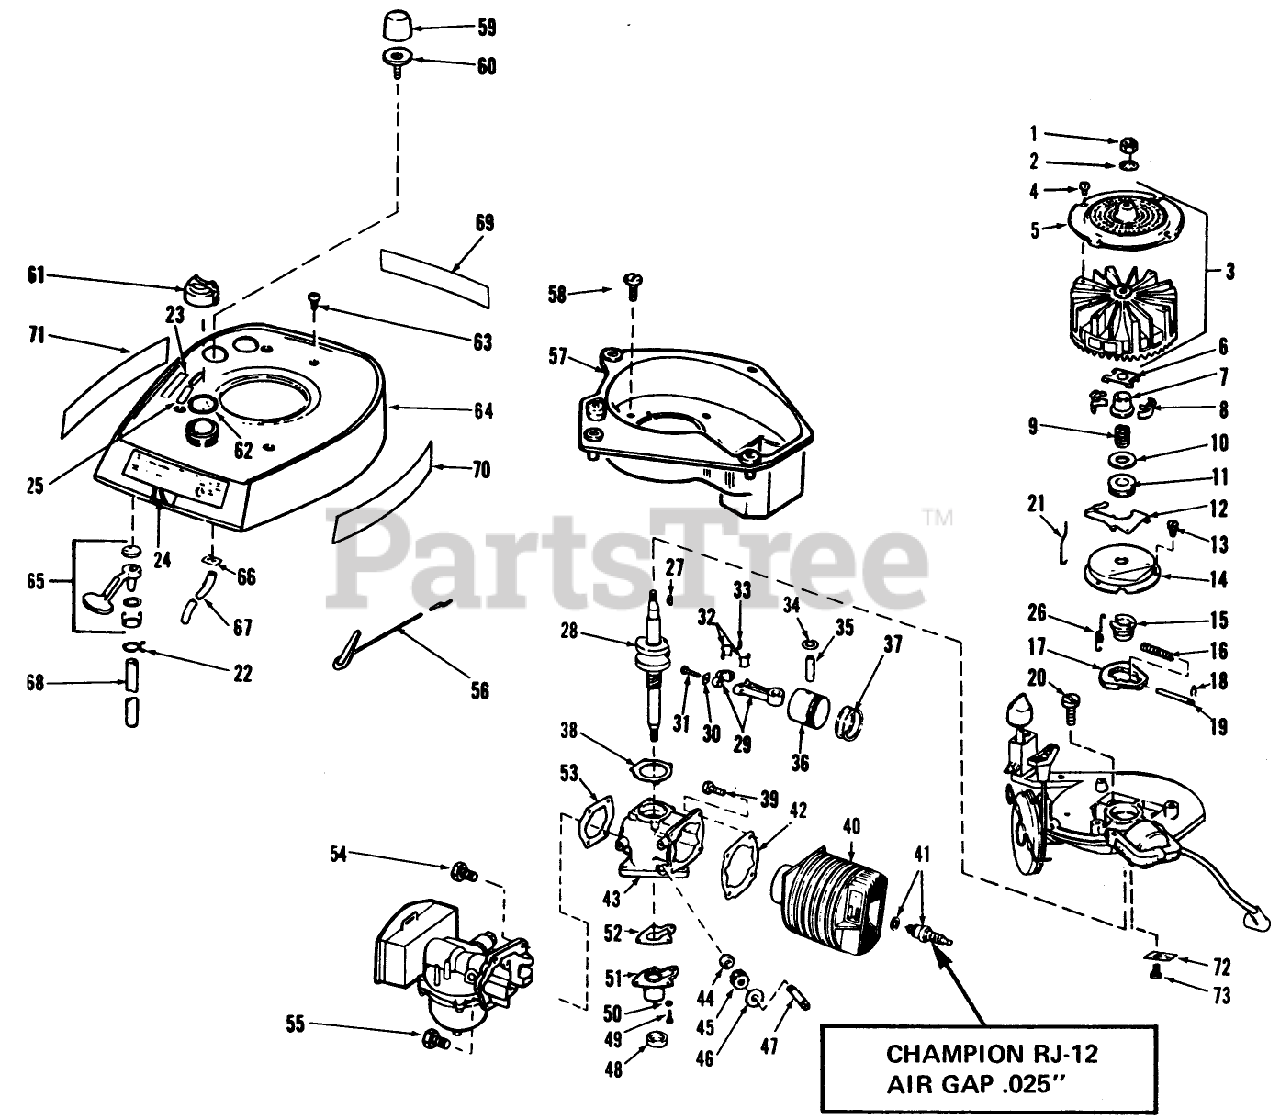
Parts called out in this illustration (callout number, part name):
1	NUT
4	SCREW F
5	FLYWHEEL SCREEN
6	YOKE S
7	COLLAR S
9	SPRING S
11	THRUST COLLAR S
12	LEVER-GOVERNOR S
13	SCREW S
14	DUST COVER S
15	SPARK ADV. S
16	SPARK ADV. SPRING S
17	FLYWEIGHT S
18	SPARK ADJ. SPRING
19	PIN,SPARK ADV. S
21	ROD S
23	Decal-Caution
24	SPRING BAR
27	KEY
31	SCREW
32	LINER ASM
34	RING-RETAINING
38	GASKET S
41	Spark Plug Gasket RJ-12
42	GASKET S
44	SEAL S
45	GEAR, DR SHAFT S
46	THRUST WASHER
48	OIL SEAL
49	SCREW
51	GEAR COVER S
52	GASKET-CVR S
53	GASKET S
54	SCREW S
55	SCREW S
56	KNOB & ROD AY. S
62	GASKET S
63	SCREW S
66	LOCKNUT S
67	TUBING S
72	TAB
73	SCREW S
